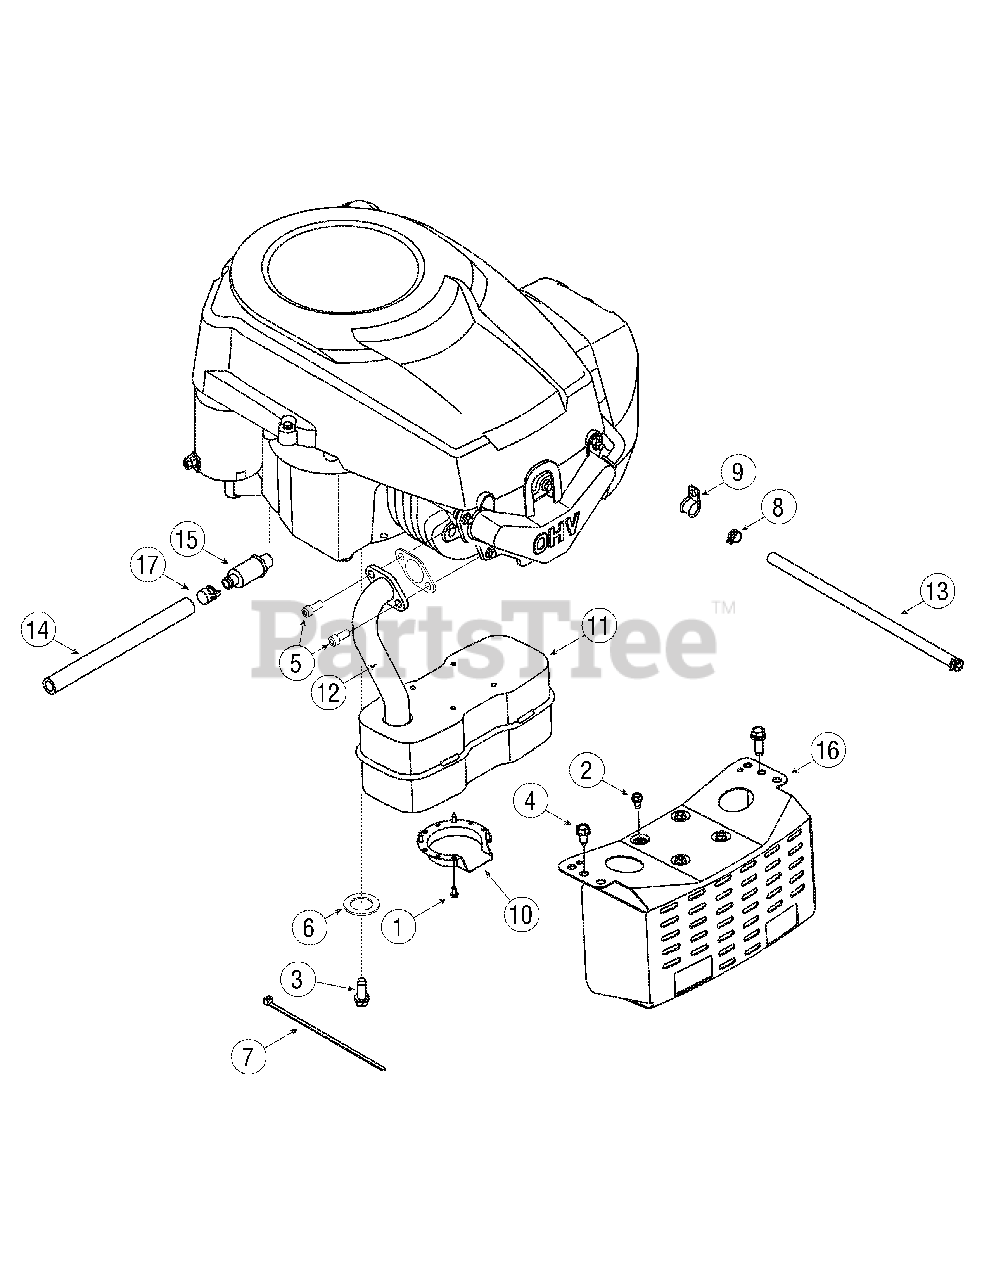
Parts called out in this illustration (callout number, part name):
1	AB Screw #8-18 x 0.5
2	TT Screw 1/4-20 x 0.5
3	TT Screw 3/8-16 x 1.00
4	AB Screw 5/16-12 x 0.5
5	Screw, 5/16-18 x .750
6	Flat Washer, 1.03 x 1.620 x .095
7	Cable Tie
8	Hose Clamp .490 dia.
9	Hose Clamp 9/16
10	Muffler Deflector
11	Single Inlet
12	Exhaust Pipe
13	Fuel Line Hose
14	OIl Drain Extension Hose
15	Oil Drain Valve
17	Oil Drain Cap
